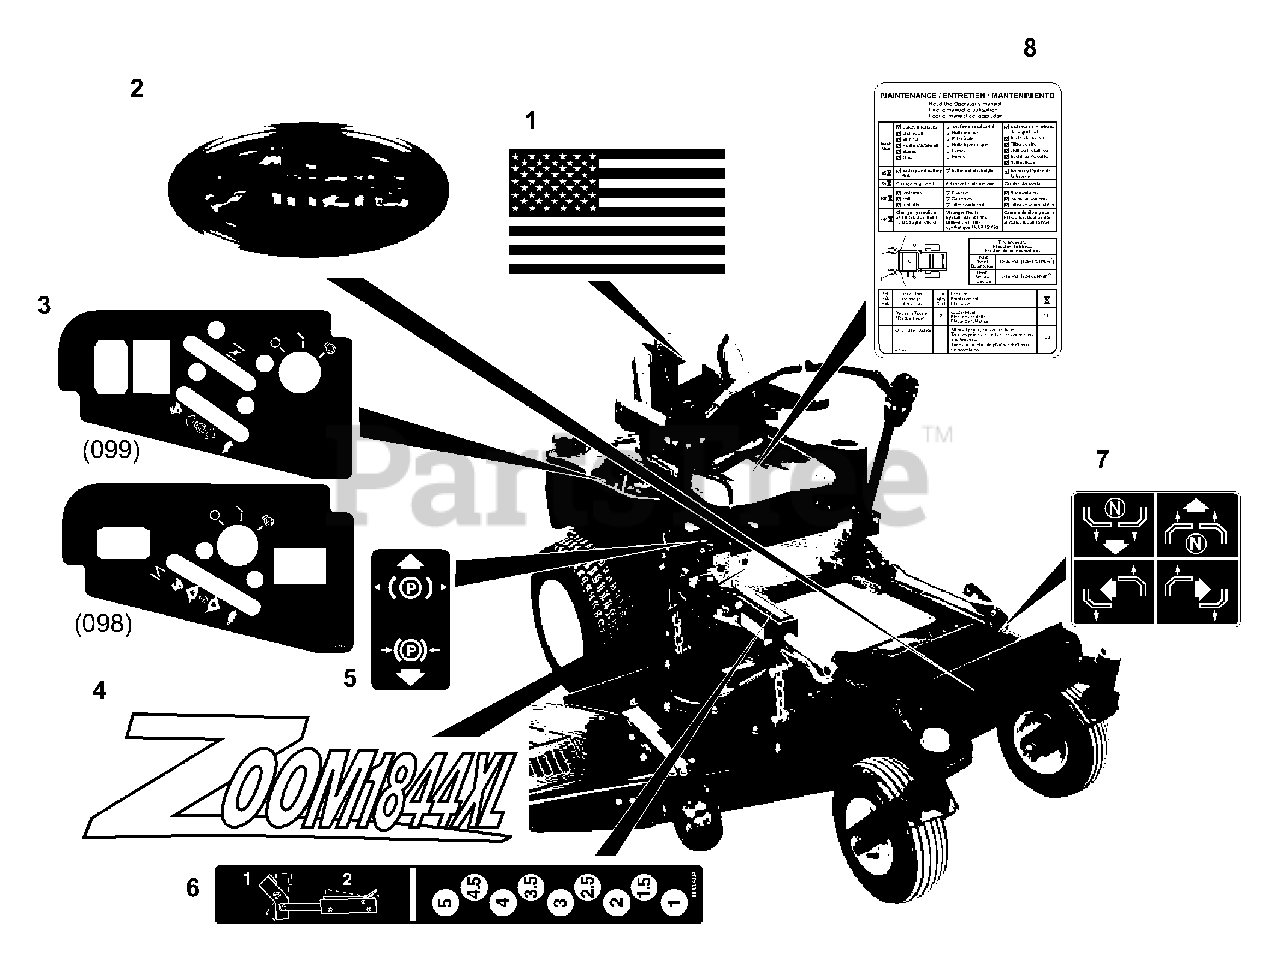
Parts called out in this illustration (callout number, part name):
1	DECAL, AMERICAN FLAG
2	DECAL, ARIENS
3	DECAL, CONTROL PANEL COMPACT Z
4	DECAL, ZOOM 1844 XL
5	DECAL, PARKING BRAKE LEVER
6	DECAL, HEIGHT OF CUT COMPACT-Z
7	DECAL, INSTRUCTIONAL-STEERING
8	DECAL, MAINTENANCE INSTRUCTION
